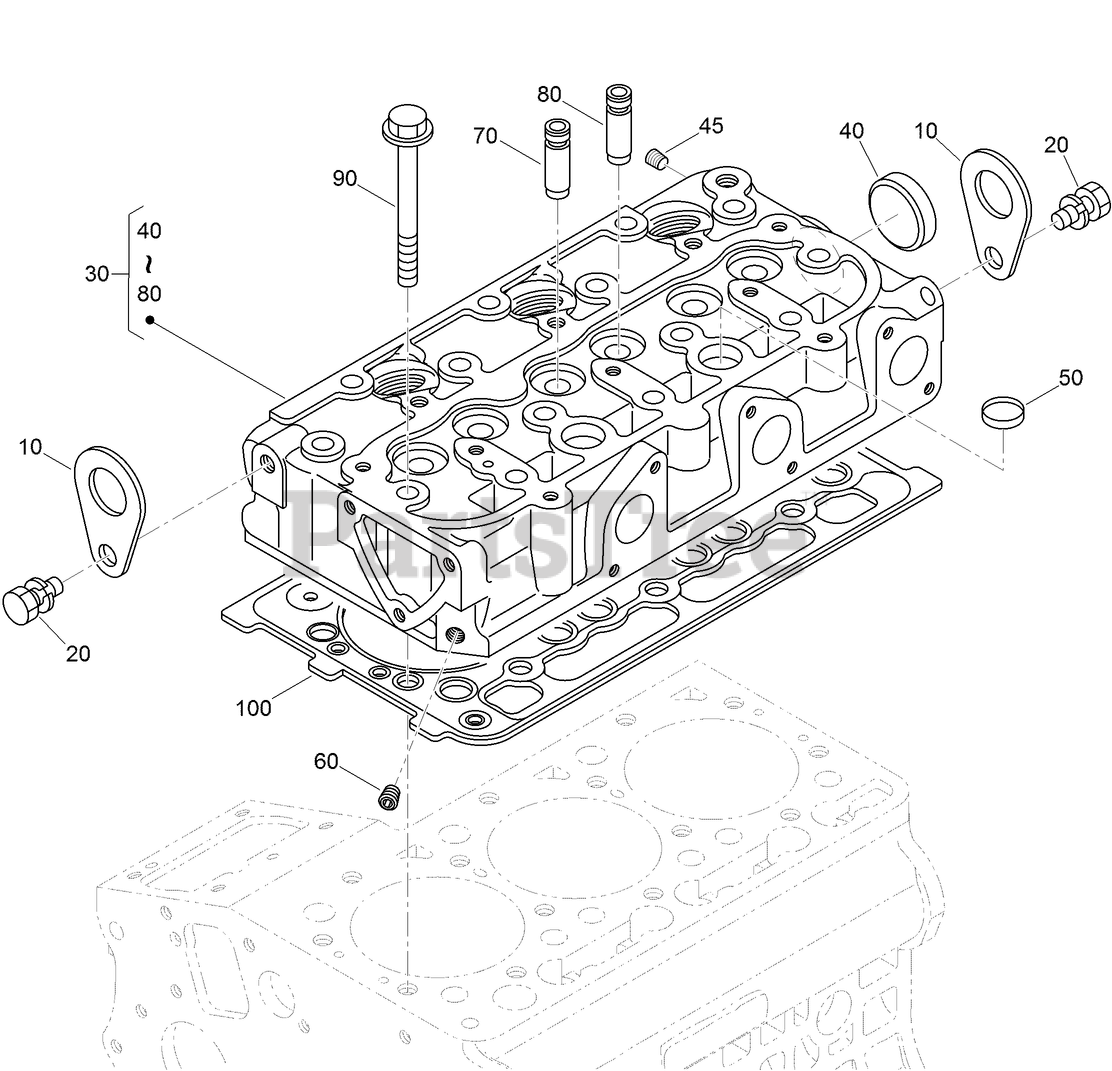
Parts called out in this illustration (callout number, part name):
10	HOOK-ENGINE
30	CYLINDER HEAD ASM
40	CAP-SEALING
50	CAP-SEALING
70	GUIDE-VALVE, INLET
80	GUIDE-VALVE, EXHAUST
90	BOLT-HEAD, CYLINDER
100	GASKET-HEAD, CYLINDER
